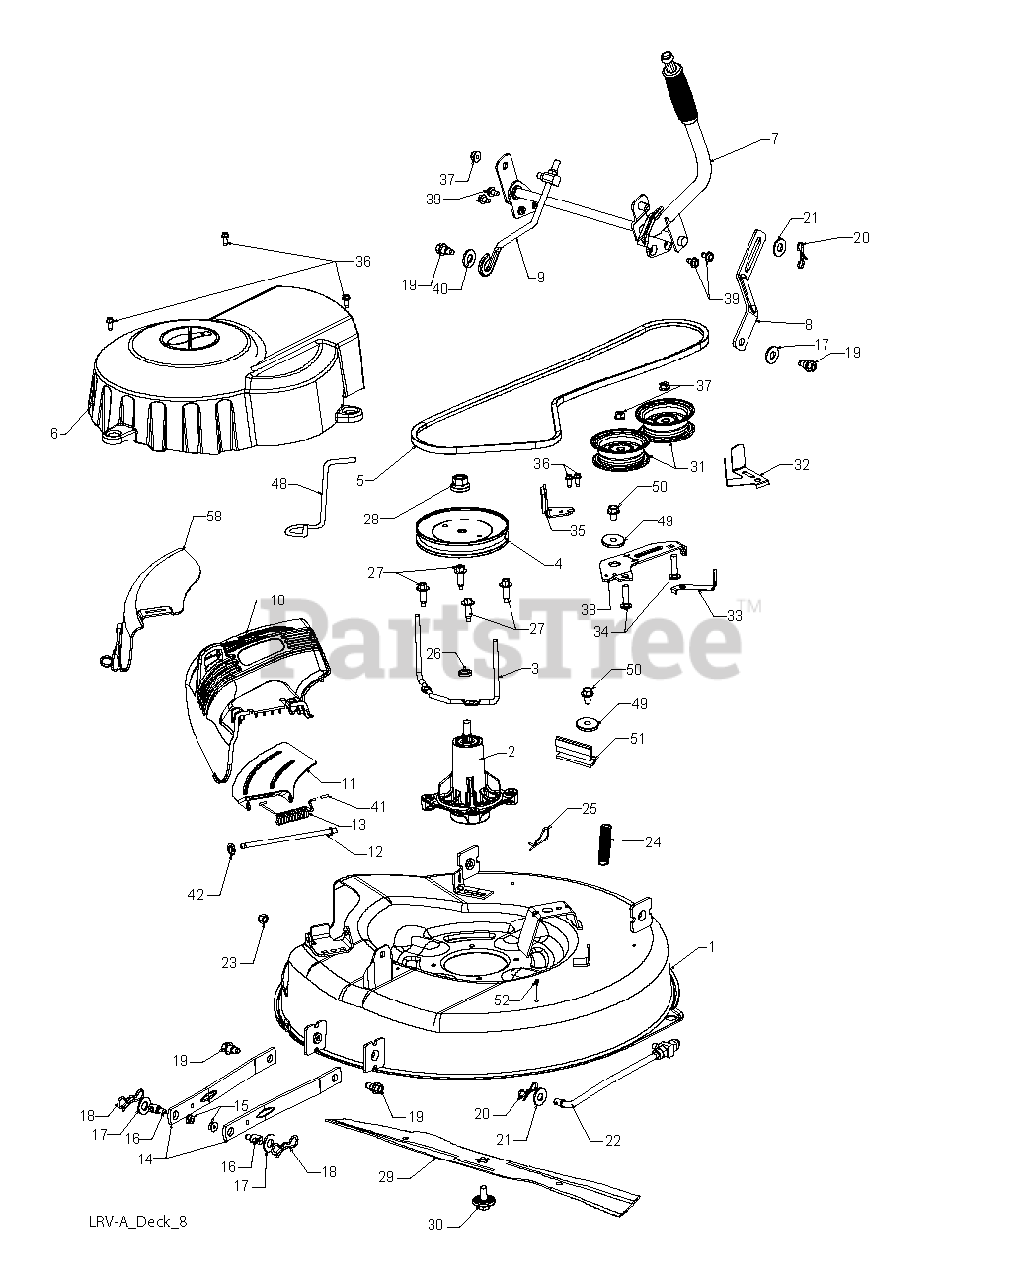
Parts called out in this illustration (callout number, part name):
1	DECK, 26"
2	MANDREL.ASM.SUB-NON.GR
3	KEEPER.BELT.MANDREL.PULLEY
4	PULLEY.MANDREL
6	COVER, MANDREL
7	LIFT.ASM.DECK.LRV
8	LINK, DECK LIFT
9	LINK.ASM.LIFT.ADJUSTABLE
11	SUPPORT, DEFLECTOR
12	ROD.HINGE
13	SPRING.TORSION.DEFLECT
14	ARMS.SUSP.MOWER.REAR.SRD
15	NUT LOCK HEX FLANGE 5/16-18
16	STUD.FASTNER.W/ANTI-ROTATE
17	WASHER.CLEAR.ZINC
18	PIN.COTTER.7/16.BOW TI.
19	BOLT.SHOULDER
20	PIN.COTTER.5/16.BOW TI
22	LINK.ASM.TOP.DECK.LRV
23	NUT LOCK FLG 3/8-16 UNC
24	SPRING.EXTENSION.DECK.LRV
26	WASHER.SPACER.MANDREL
27	SCREW, WASHER HEAD
28	NUT.FLANGE.LOCK.TOP
29	BLADE.LRV.BAGGING
30	BOLT.WASHER.ASM.7/16-2
31	PULLEY.IDLER.48"PRIMARY
32	GUARD, BELT
33	KEEPER BELT
34	BOLT.3/8-16X1.50
35	ARM BRAKE MOWER RH
36	SCREW.1/4-20X5/8
37	NUT LOCK FLG 3/8-16 UNC
38	ARM, IDLER
39	SCREW LT
41	CAP-SLEEVE LT
42	NUT PUSH M
48	KEEPER.BELT
49	SPACER.RETAINER
50	SCREW 3/8-16X1
51	BUMPER.HOOD.TEX.HUSQVARNA
52	SCREW 3/8-16X1/2
58	COVER.ASM.MULCH.26"LRV
